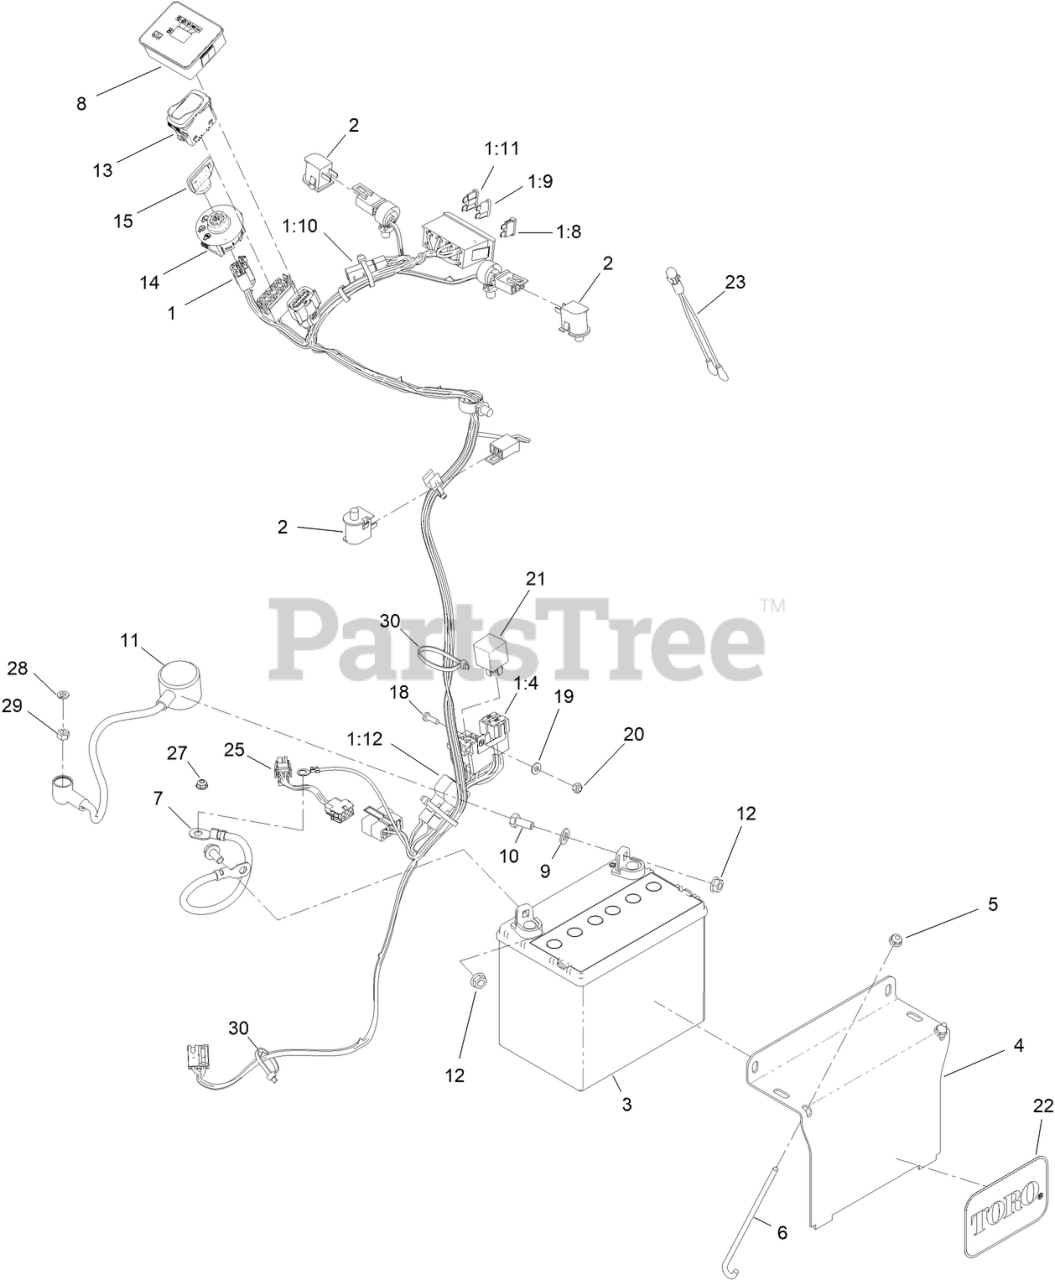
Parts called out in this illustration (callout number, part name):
1	HARNESS-WIRE, GRANDSTAND
1:4	FUSE-BLADE, 20 AMP
1:8	FUSE-BLADE, 15 AMP
1:9	FUSE-BLADE, 10 AMP
1:10	CAP-PLUG
1:11	FUSE-BLADE, 5 AMP
2	SWITCH-BAIL
3	BATTERY-DRY
4	BRACKET-HOLD DOWN, BATTERY
5	NUT-HF
6	BOLT-HOLDDOWN
7	CABLE-BATTERY, BLACK
8	MODULE-METER, HOUR
9	WASHER-PLAIN
10	SCREW-HH
11	CABLE-BATTERY, POSITIVE
12	NUT-HHF, SMOOTH
13	SWITCH-ROCKER, (ON)-ON-OFF
14	SWITCH-IGNITION
15	KEY-IGNITION
18	SCREW-PPH
19	WASHER-FLAT
20	NUT-LOCK, NI
22	DECAL
23	INDICATOR-LED, RED
25	HARNESS-WIRE, JUMPER
27	NUT-HF
28	WASHER-LOCK, SPRING
29	NUT-HEX
30	TIE-CABLE
